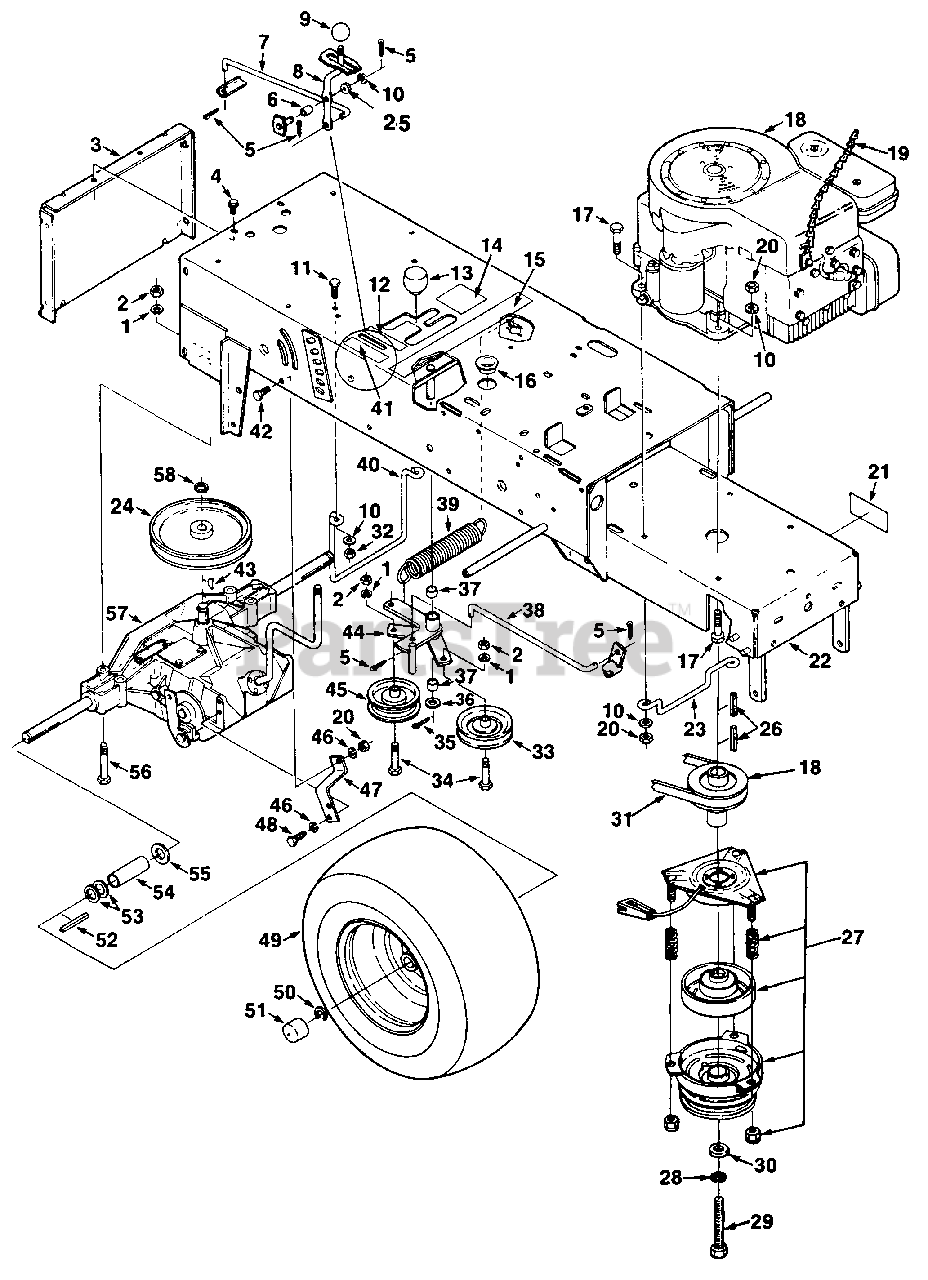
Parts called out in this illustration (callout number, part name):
1	WASHER- Lock (3/8")
2	NUT- Hex (3/8-16)
3	BRACKET- Hitch
4	BOLT- (1/4-20 x 9/16")
5	PIN- Cotter (3/32 x 3/4")
6	SPACER- Lever
7	ROD- Hi-lo sect.
8	LEVER- Hi-lo
10	WASHER- Flat (5/16")
11	SCREW- Hex hd. cap (5/16-18 x 7/8")
12	DECAL- Second & Reverse
13	KNOB- Shift lever
14	DECAL- First & Third
15	DECAL- Warning
16	BUSHING- Snap
17	SCREW- Hex hd. cap (5/16-18 x 1 3/4")
18	PULLEY- Drive
19	CHAIN- Restraining
20	NUT- (5/16-18)
21	DECAL- Warning
22	FRAME ASSY.
23	GUIDE- Front belt
24	PULLEY- Drive
25	WASHER- Shakeproof
27	BRAKE- Electric clutch
28	WASHER- Lock hvy. (7/16")
29	SCREW- Hex hd. cap (7/16-20 x 3")
30	CLUTCH- Retainer
31	BELT- Traction drive
32	NUT- Hex centerlock (5/16-18)
33	IDLER- Inside
34	SCREW- Hex hd cap (3/8-16 x 1 3/4")
35	PIN- Cotter (3/16 x 1")
36	WASHER- Flat (17/32")
38	ROD- Idler actuator
39	SPRING- Extension
40	GUIDE- Rear belt
41	DECAL- Hi-Lo
42	SCREW- Hex hd. cap (5/16-18 x 5/8")
43	KEY- (3/16 x 3/4")
44	CLUTCH BEARING ASSY.
45	IDLER- Backside
46	WASHER- Lock hvy. (5/16")
48	SCREW- (5/16-18 x 3/4")
49	REAR WHEEL ASSY.
50	RING- Retaining
51	HUB CAP- Rear wheel
52	KEY- (3/16 x 3/16 x 2 1/2")
54	SPACER- Rear wheel
55	WASHER- Flat (13/16")
56	SCREW- Hex (3/8-16 x 2 3/4")
57	TRANSAXLE- 6 Speed
58	RING- Retaining
